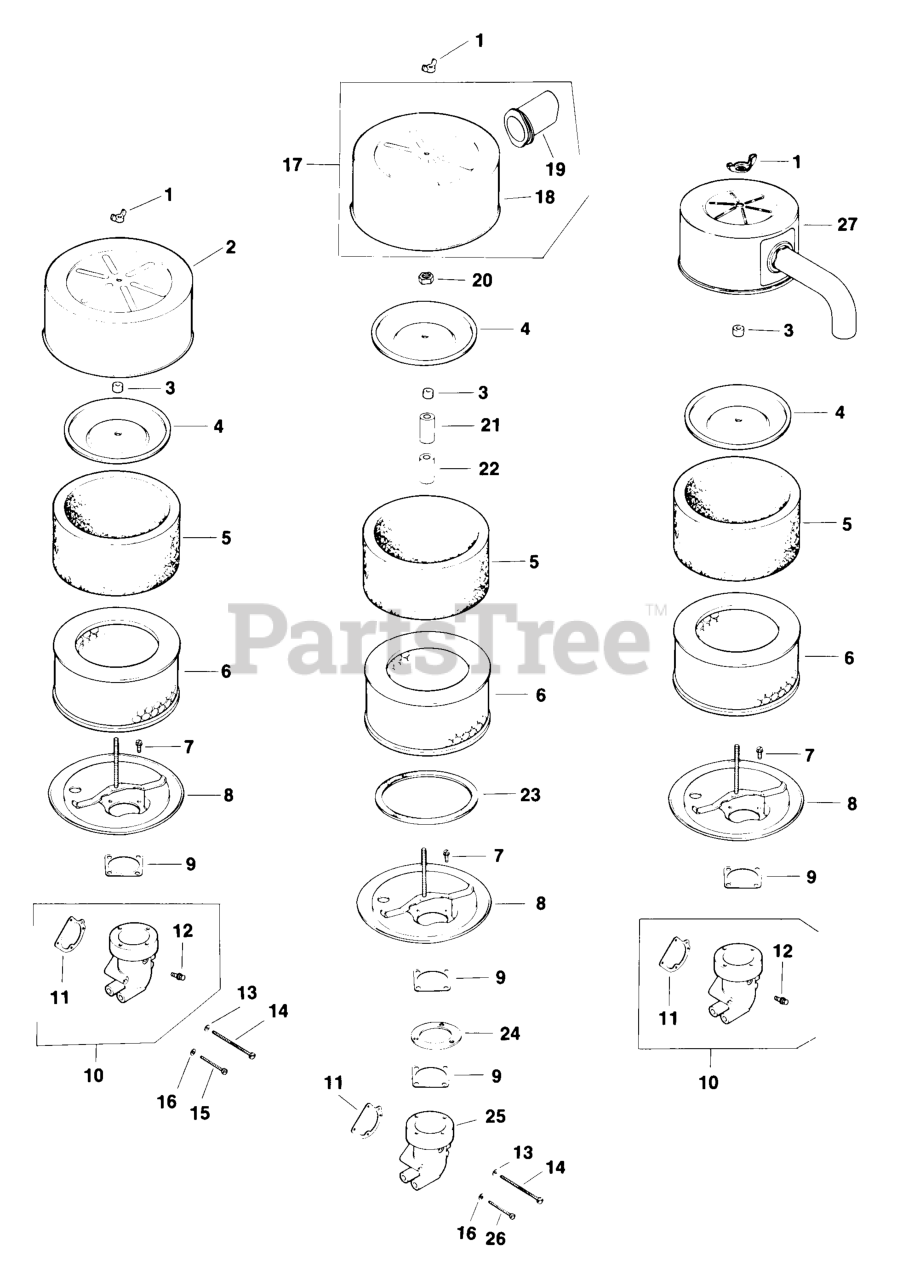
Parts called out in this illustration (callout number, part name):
1	Wing Nut 1/4-20
2	Cover, Air Cleaner
3	Seal, Element Cover
4	Cover, Air Cleaner Element
5	Precleaner
7	Screw, Hex. Wash. Hd. 10-32x9/16"
8	Base, Air Cleaner
9	Gasket, Air Cleaner
10	Kit, Elbow
11	Gasket, Elbow
12	Screw, Hex. Wash. Hd. 1/4-20x5/8"
13	Washer, Plain #10
14	Screw, Sltd. Pan Hd. 10-32x2-1/4"
15	Screw, Sltd. Pan Hd. 10-32x1-1/2"
16	Washer, I.T. #10
